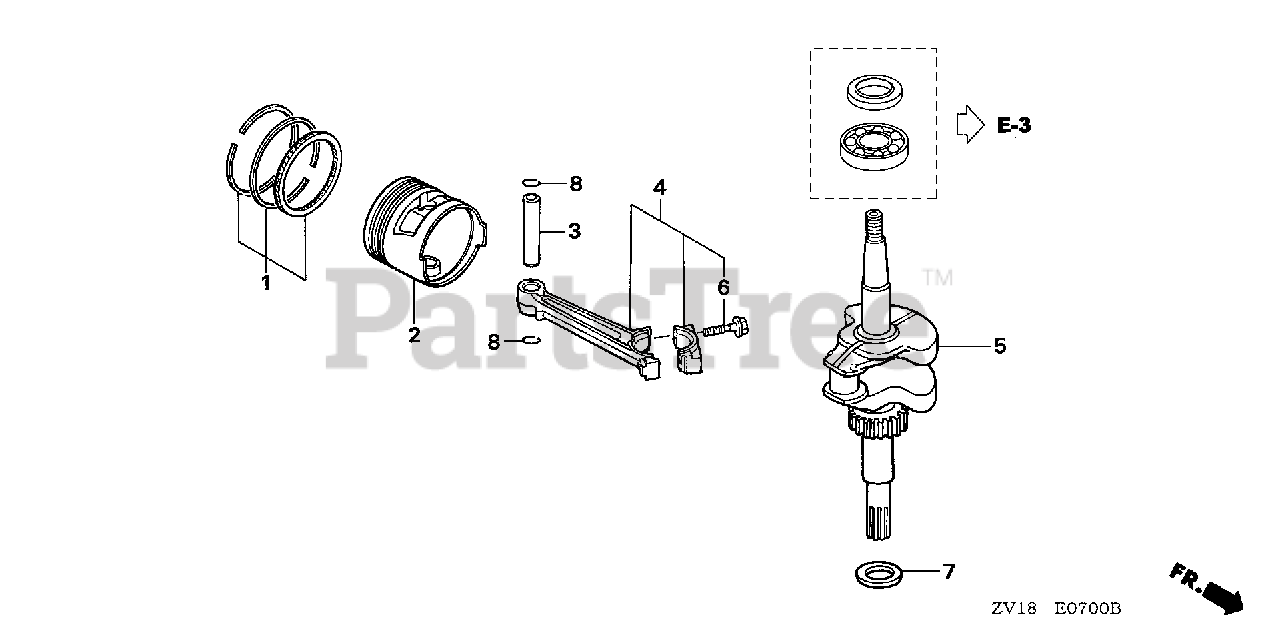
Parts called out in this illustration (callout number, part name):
1	RING SET, PISTON (STD) (TEIKOKU)
1	RING SET, PISTON (OS 0.25) (Honda Code 7066418). (NIPPON)
1	RING SET, PISTON (0.75) (Honda Code 7066442). (TEIKOKU)
1	RING SET, PISTON (0.75) (Honda Code 7066459). (NIPPON)
3	PIN, PISTON
4	ROD ASSY., CONNECTING
5	CRANKSHAFT
6	BOLT, CONNECTING ROD
6	BOLT, CONNECTING ROD (IDENT MARK Z)
7	WASHER C, THRUST (25MM)
8	CLIP, PISTON PIN (18MM)
